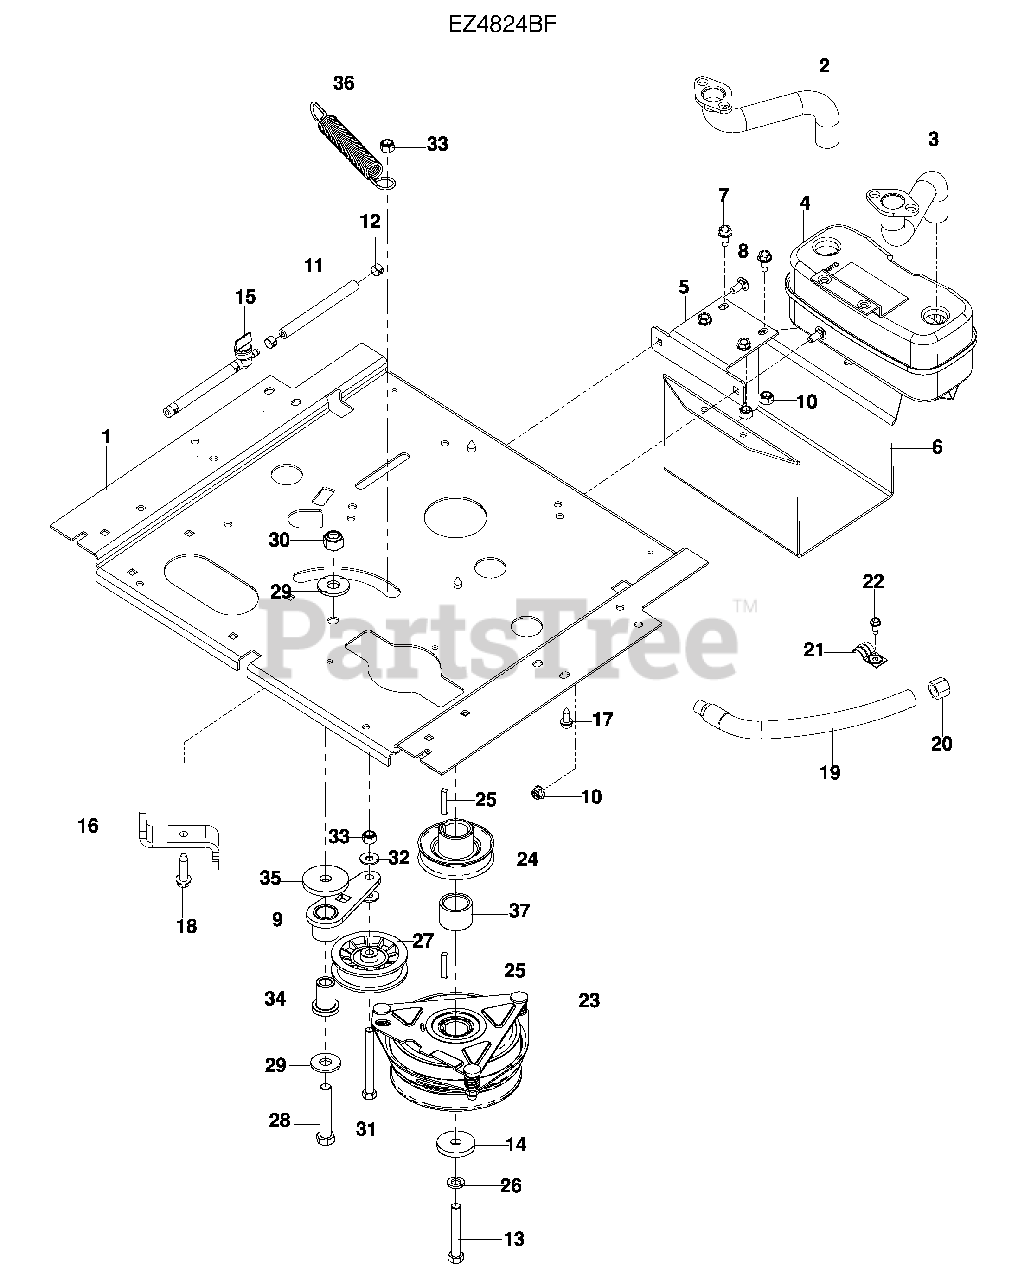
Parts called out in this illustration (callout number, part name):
1	PLATE, ENGINE
2	EXHAUST TUBE, RT
3	EXHAUST TUBE, LT
4	MUFFLER ASM TWIN
5	BRACKET, MUFFLER
6	GUARD, MUFFLER
7	BOLT 5/16-18 x ¾ THD FRM
8	RHSNB 5/16-18 x ¾
9	ARM, IDLER
10	NUT 5/16-18 FLANGE NYLOC
11	FUEL LINE 5"
12	CLAMP, HOSE
13	HCS 7/16-20 x 2¾
14	WASHER, HEAVY
15	VALVE, FUEL
16	STOP, CLUTCH
17	HHFS 3/8-16 x 1 THD FRM
18	BOLT 3/8-16 x 1½ THD FRM
19	HOSE, DRAIN
22	SCREW ¼-20 x 5/8 SLF TAP
23	CLUTCH, 150 FT/LBS
24	PULLEY, DRIVE
25	KEY ¼ SQ x 2
26	WASHER 7/16 SLW
27	PULLEY, IDLER
28	HCS ½-13 x 2¾
29	WASHER ½ FLAT
30	NUT ½ HEX NYLOC
31	HCS 3/8-16 x 3½ TPBLT
32	WASHER 5/16 STD FLAT
33	NUT 3/8-16 HEX NYLOC
34	PIVOT, IDLER
35	WASHER, HEAVY
36	SPRING, DECK DRIVE
37	SPACER, CLUTCH
